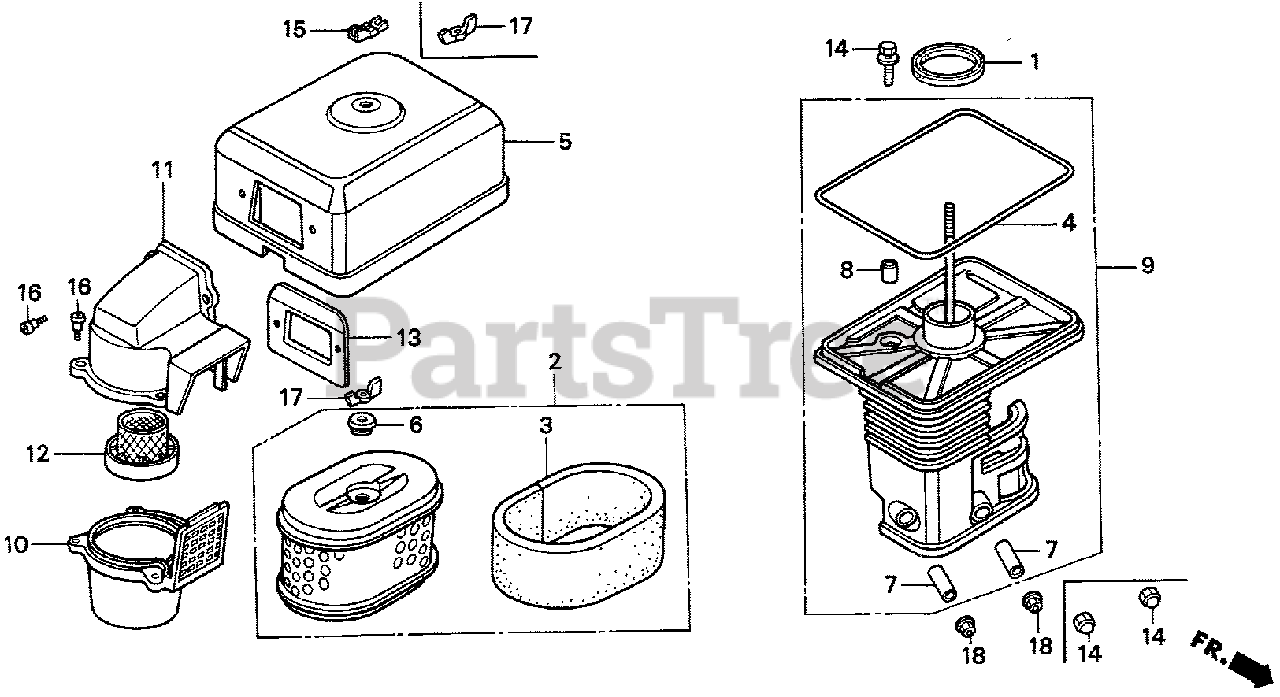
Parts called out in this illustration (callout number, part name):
1	GASKET, ELBOW
2	ELEMENT, AIR CLEANER (DUAL)
3	FILTER (OUTER)
3	FILTER (OUTER) (NOT AVAILABLE)
4	GASKET, AIR CLEANER COVER
5	COVER, AIR CLEANER (DUAL)
6	GROMMET, AIR CLEANER
7	COLLAR, AIR CLEANER
8	COLLAR B, AIR CLEANER
9	ELBOW, AIR CLEANER
10	CASE, PRE AIR CLEANER
11	CAP, PRE AIR CLEANER
12	GUIDE, PRE AIR CLEANER
13	PLATE, PRE AIR CLEANER
14	NUT, CAP (6MM)
15	WINGNUT, AIR CLEANER COVER
15	WINGNUT (6MM)
16	BOLT, MUDGUARD
17	WINGNUT, TOOL BOX SETTING
18	NUT, FLANGE (6MM)
NI	BOLT, FLANGE (6X20)
